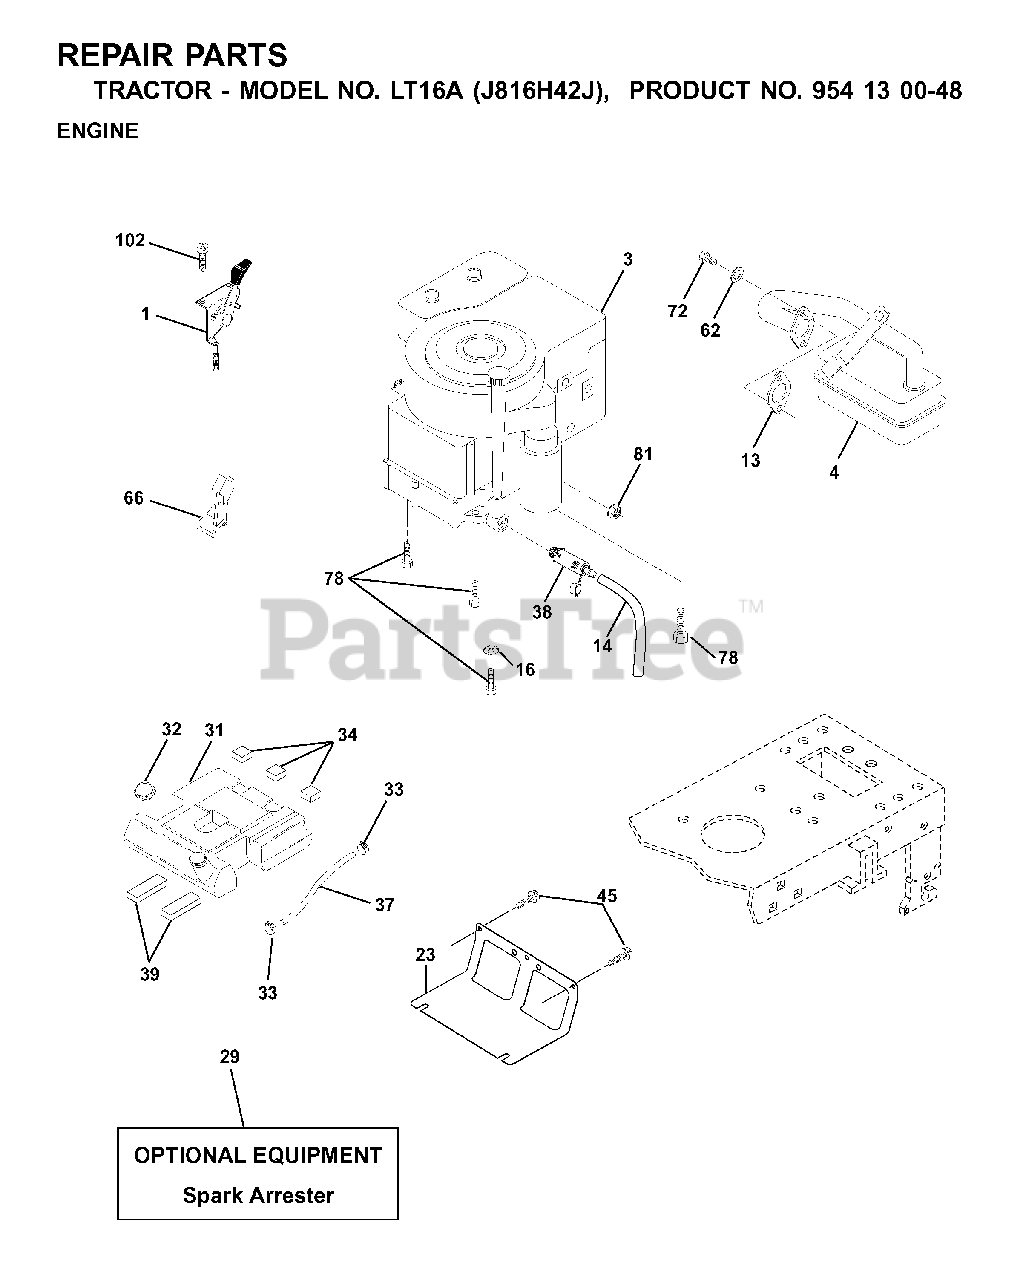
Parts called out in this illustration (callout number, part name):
13	REPL BY 532 27 22-93
14	TUBE, DRAIN OIL ASM.
16	LOCKWASHER
23	SHEILD.BROWNING.DBR.GUARD
29	ARRESTER SPARK (OPTIONAL)
31	TANK.FUEL(3.5.GAL)
32	FUEL CAP
33	HOSE CLAMP
34	PAD-SPACER LT
38	PLUG, OIL DRAIN EASY
39	PAD IDLER TI
45	SCREW, 3/8-16X3/4
62	LOCKWASHER
66	STOP THROTTLE
72	SCREW
78	SCREW.3/8-16
81	NUT
102	SCREW
